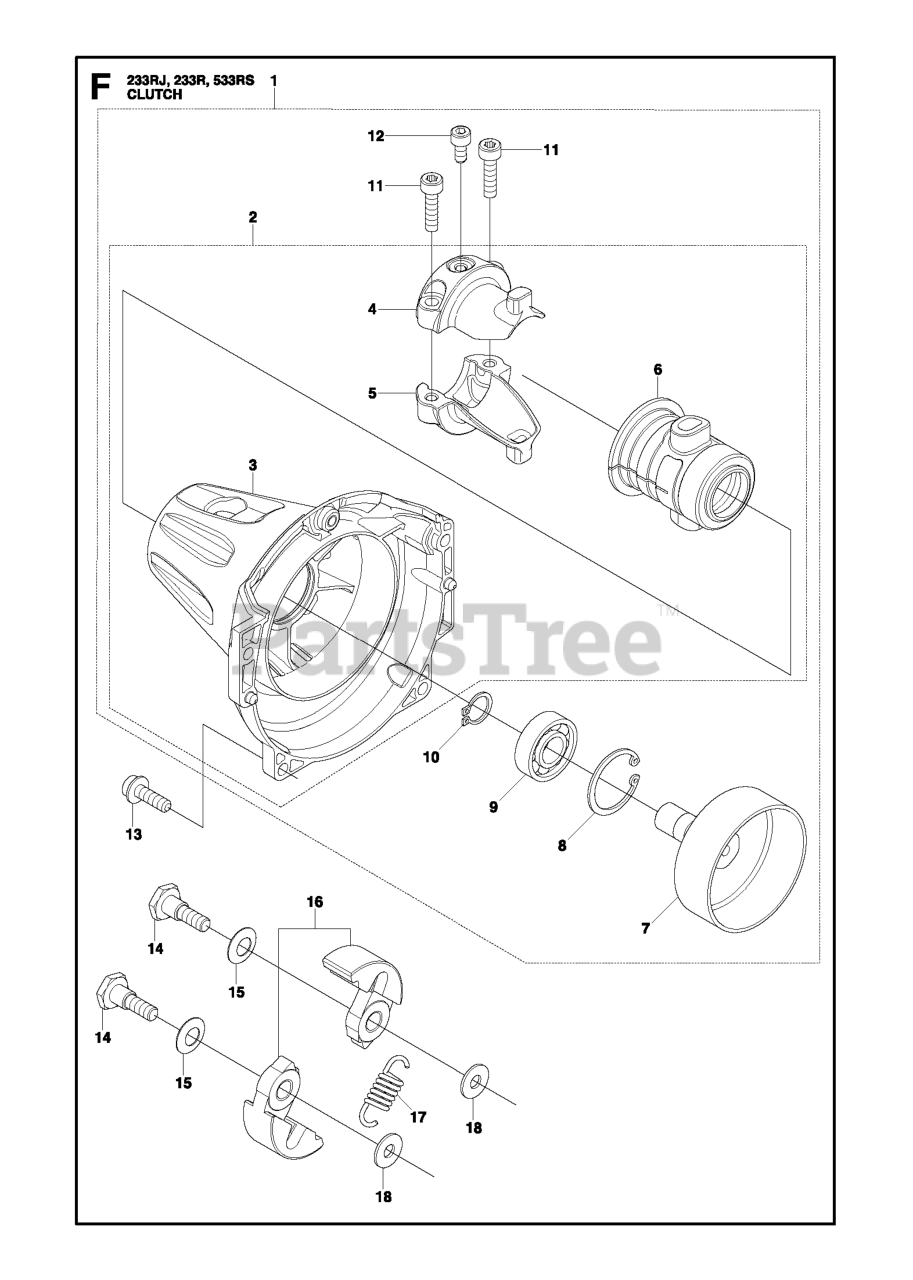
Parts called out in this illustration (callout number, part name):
1	HOUSING ASSY
2	HOUSING COMP.
4	BRACKET (A) (RPLS T170031211)
5	BRACKET (B)
7	DRUM (RPLS 481031120-22)
11	BOLT
